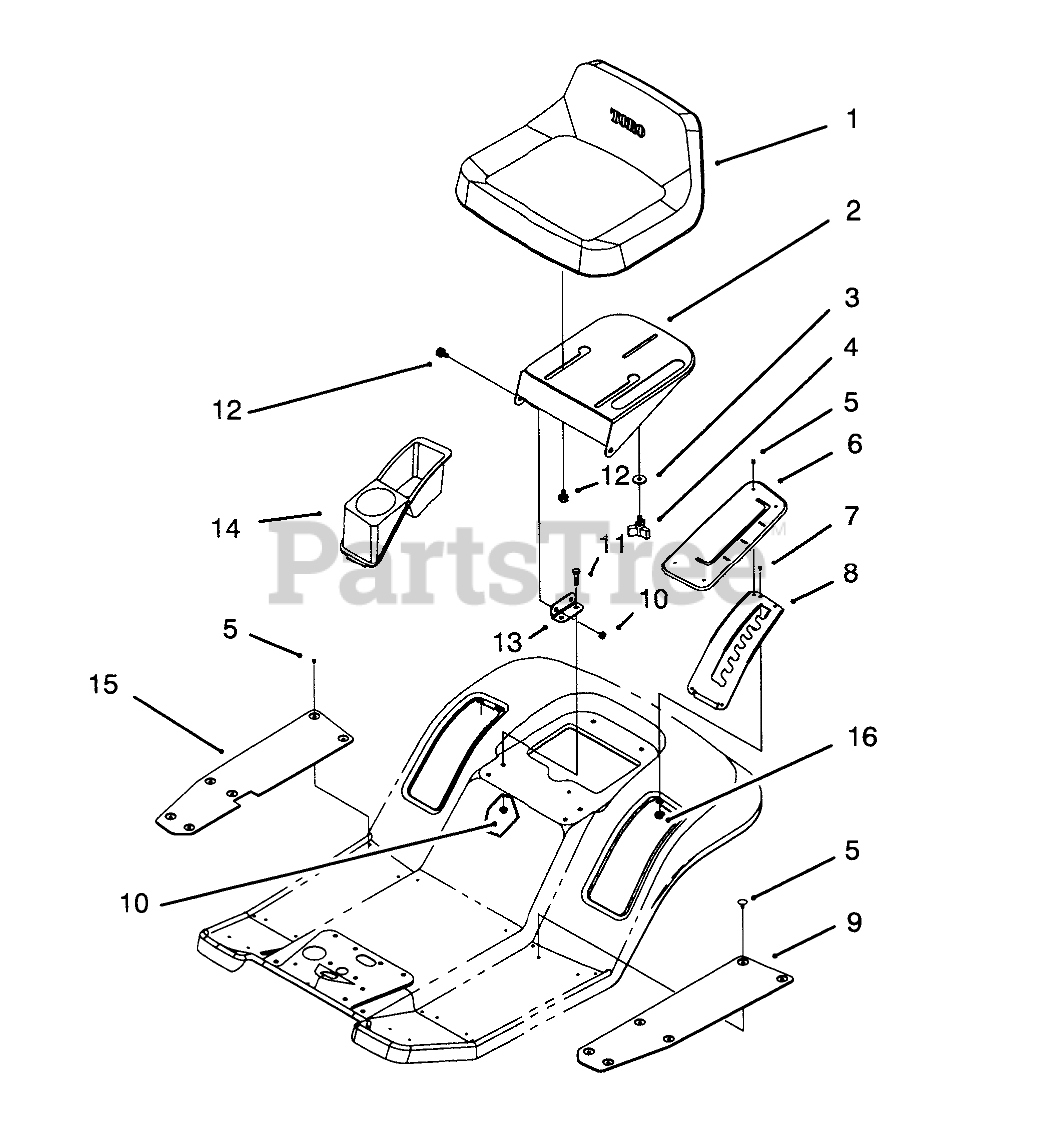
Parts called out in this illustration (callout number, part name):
1	SEAT
2	Support-Seat
3	WASHER-PIVOT
5	FASTENER-PANEL
6	COVER-HOC
7	RIVET-BLIND
8	Gate-H.O.C.
9	MAT-FOOT, LH
10	NUT-LOCK, NI
11	SCREW-HH
12	BOLT-SHOULDER
13	Bracket-Seat Hinge
14	TRAY-FENDER
15	MAT-FOOT, RH
16	WASHER-PLAIN
